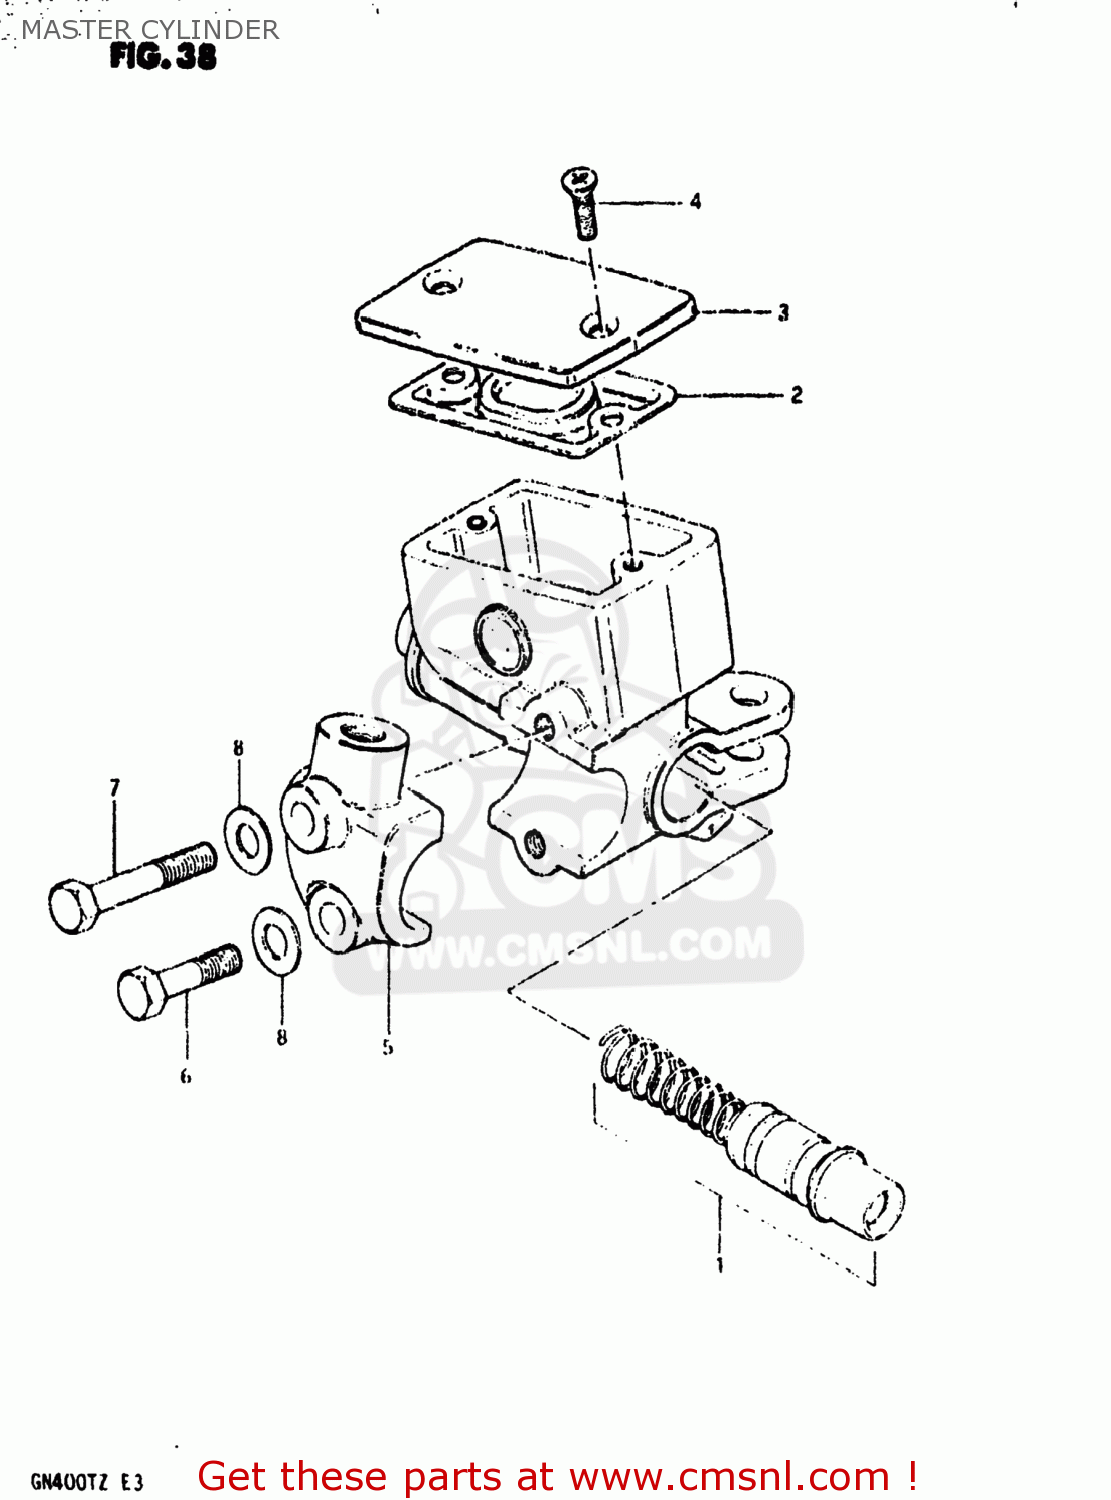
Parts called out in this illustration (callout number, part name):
1	PISTON & CUP SET
2	3
3	CAP
4	SCREW
5	HOLDER
6	BOLT
7	BOLT 6X40
8	LOCK WASHER
